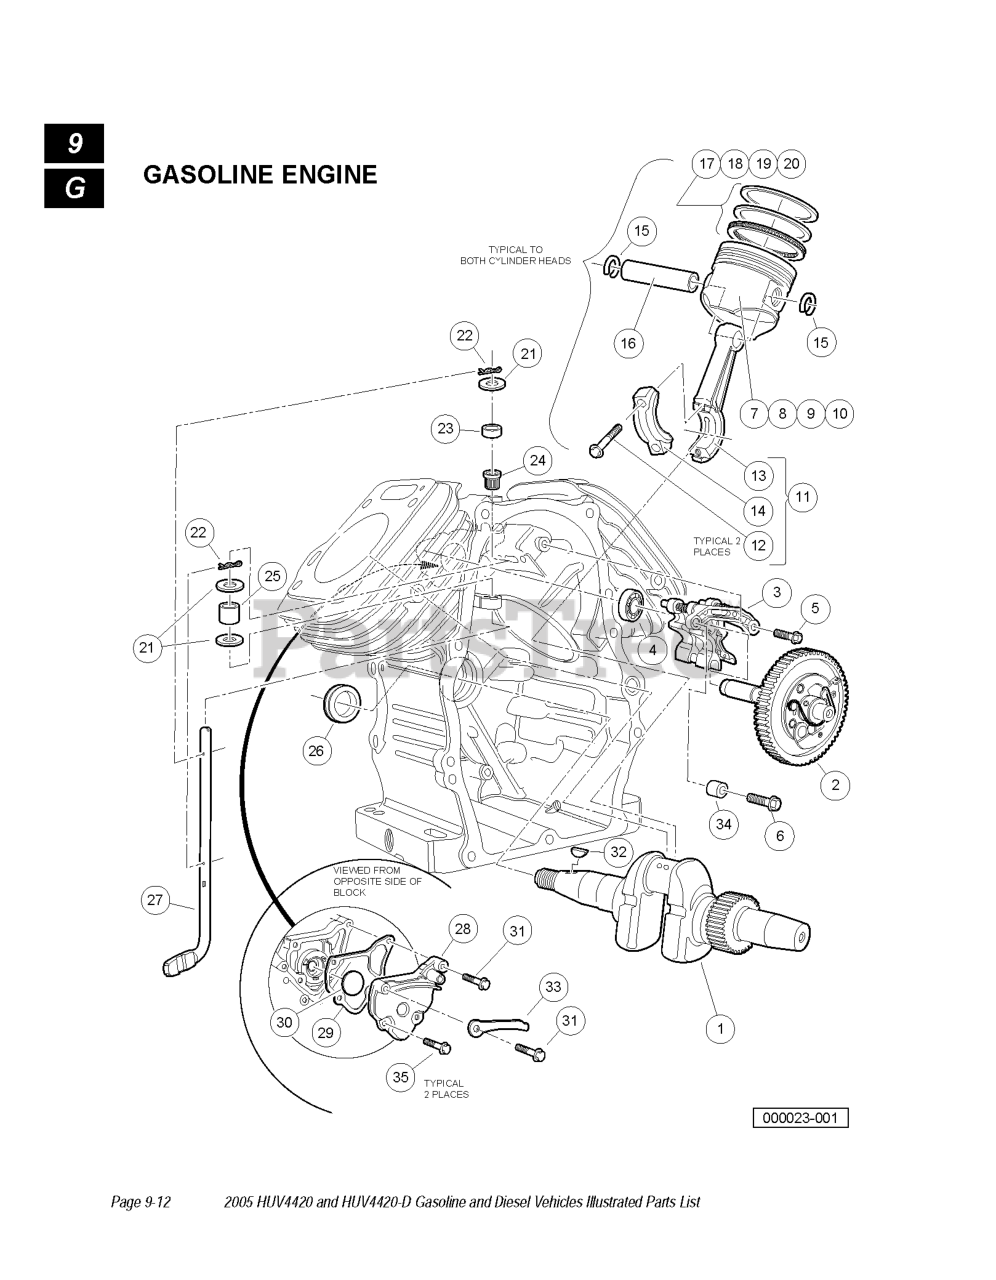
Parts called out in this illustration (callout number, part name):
1	CRANKSHAFT
2	CAMSHAFT ASSY.
3	LIFTER ASSY., VALVE
4	BEARING, RADIAL BALL, 6003
5	BOLT, FLANGE, M5 X 1 X 16
6	BOLT, FLANGE, M6 X 1 X 25
7	PISTON, STD
8	PISTON, OS 0.25
9	PISTON, OS 0.50
10	PISTON, 0.75
11	ROD ASSY., CONNECTING
12	BOLT, CONNECTING ROD, 6 X 37
15	2LIP, PISTON PIN, 18MM
16	PIN, PISTON
17	RING SET, PISTON, STD
18	RING SET, PISTON, OS 0.25
19	RING SET, PISTON, OS 0.50
20	RING SET, PISTON, OS 0.75
21	WASHER, PLAIN, M8
22	PIN, LOCK, 8MM
23	BEARING, NEEDLE, 8 X 12.7 X 11
24	OIL SEAL, 8 X 14 X 5
25	BEARING, NEEDLE, 8 X 12 X 10
26	OIL SEAL, 38 X 58 X 9
27	SHAFT, GOVERNOR ARM
28	COVER, BREATHER
29	GASKET, BREATHER COVER
30	VALVE, BREATHER
31	BOLT, FLANGE, M6 X 1 X 32
32	KEY, SPECIAL WOODRUFF, 25 X 18
33	CLAMP, WIRE
34	PIN A, DOWEL
35	BOLT, FLANGE, 6 X 16
